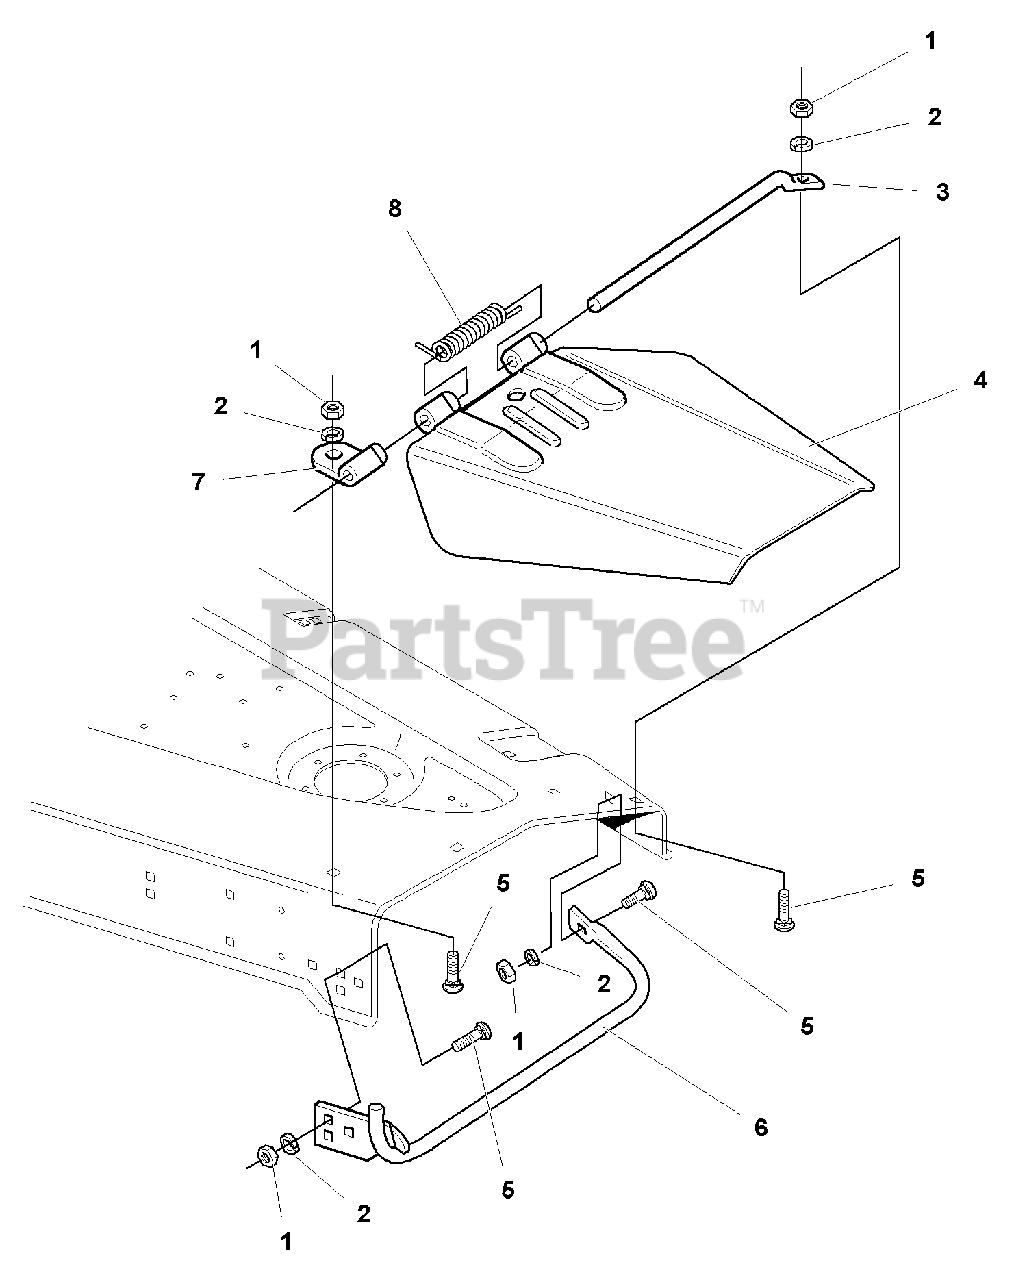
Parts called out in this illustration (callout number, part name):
1	NUT, Hex, 3/8-16
2	LOCKWASHER, 3/8
4	DEFLECTOR ASSEMBLY
5	CARRIAGE BOLT, 3/8-16 x 1
6	STONE GUARD
7	BRACKET, Hinge
8	SPRING, Torsion
